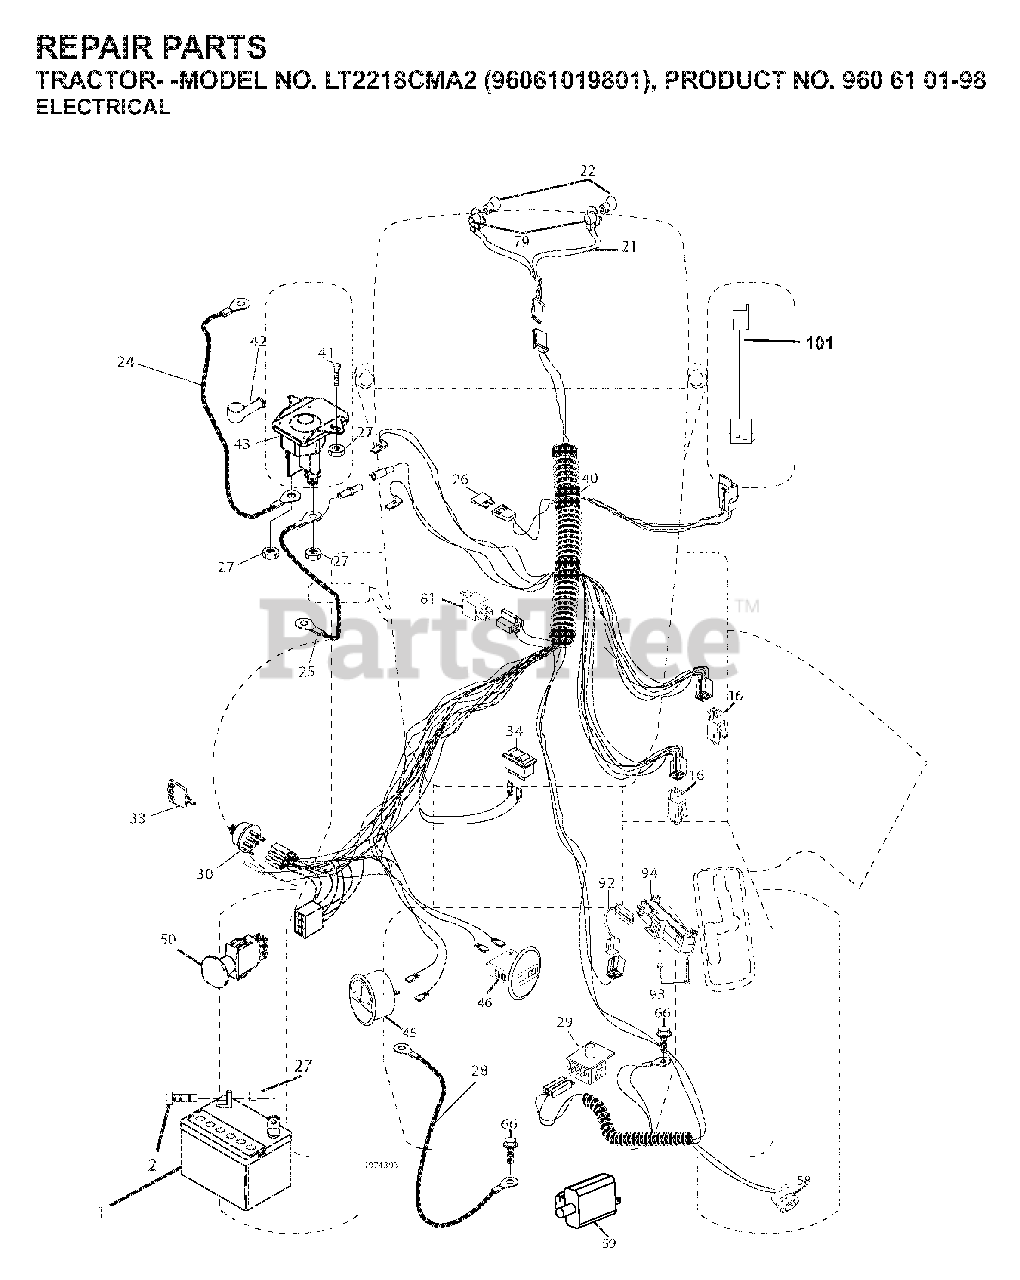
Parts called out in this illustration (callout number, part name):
1	BATTERY 12V .35 AMP
16	SWITCH INTERLOOK PUSH-IN
21	HARNESS.W/LIGHT SOCKET
22	LIGHTBULB
24	BATTERY CABLE GT
25	CABLE BATTERY
26	FUSE 20AMP
27	NUT
28	CABLE GROUND
29	SWITCH.SEAT.DP W/RAMPS
30	SWITCH.IGN.DELTA.W.LGH.ROS
33	KEY.CHAIN.BLISTER.PACK.GEN.INT
34	SWITCH LT
42	TERMINAL COVER
43	SOLENOID.W/BRASS.PLUNG
46	HOURMETER SNAP-IN
50	PTO SWITCH
58	BUZZER
79	BULB HOLDER ASM.
81	RELAY.ASSY.T
92	HARNESS.PIGTAIL.CONSLE
93	SCREW.PLASTITE
94	MODULE.REVERSE.ROS
101	PIGTAIL.MATNLK.NEW.HAR
